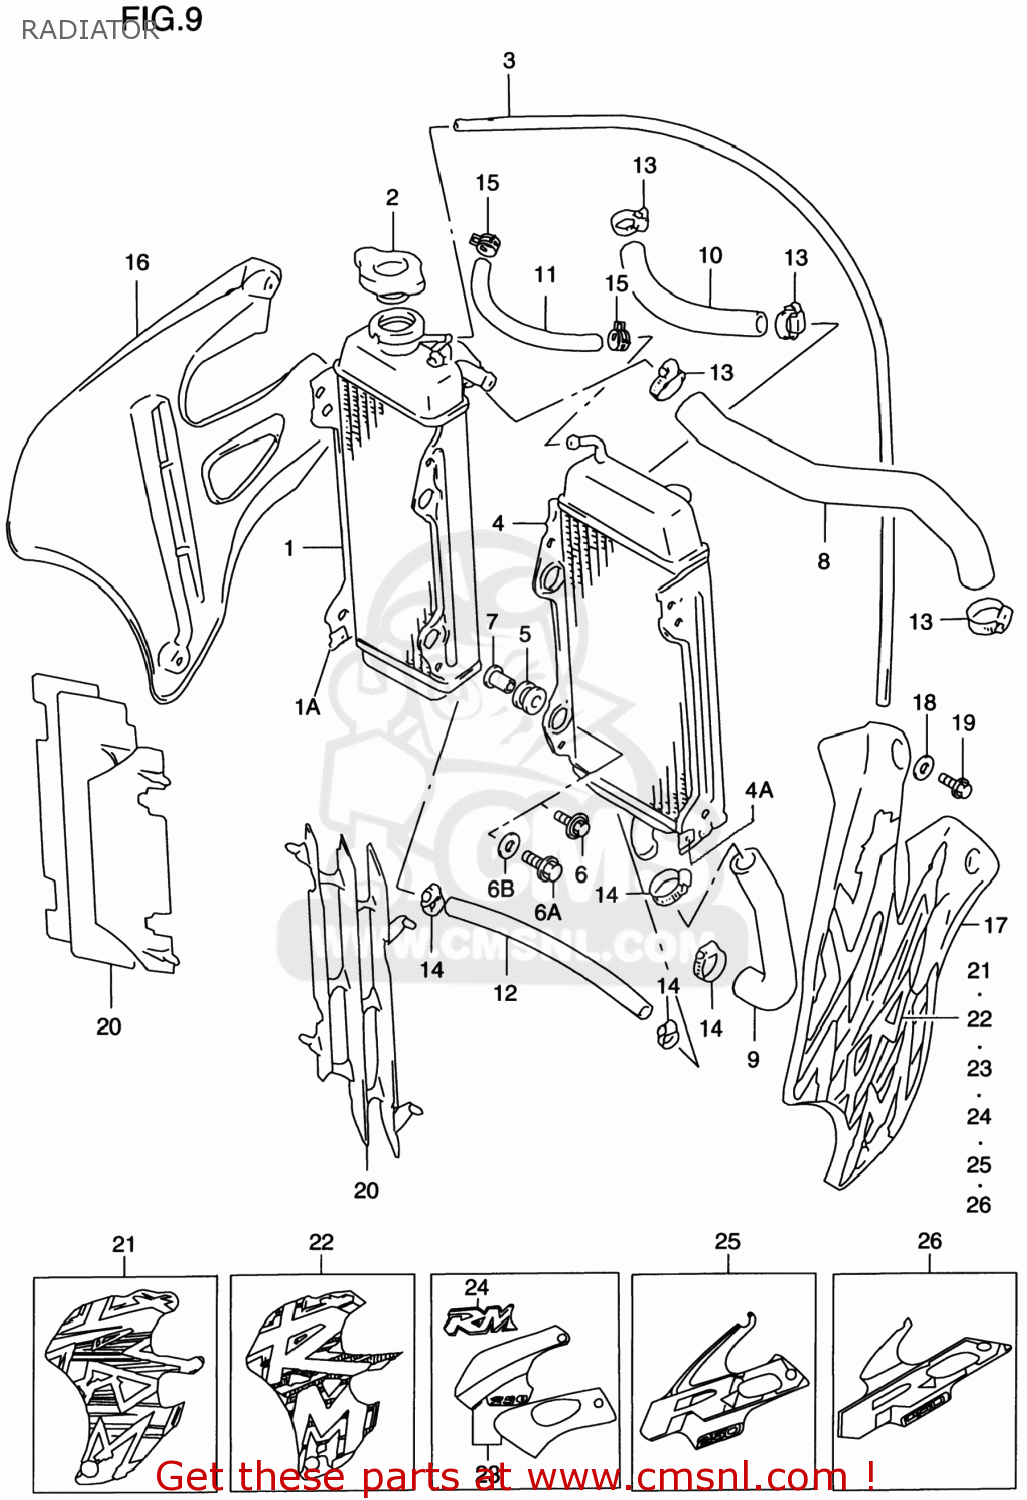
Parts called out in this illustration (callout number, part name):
1	RADIATOR,WATER,R
1-A	NUT
2	CAP,RADIATOR
3	HOSE(5X8X2000)
4	RADIATOR,WATER,L
4-A	NUT
5	CUSHION,RADIATOR LWR
6	BOLT(6X25)
6A	SCREW
6B	WASHER(6.5X24X1.2)
7	SPACER(6.5X10.5X14.1)
8	HOSE,RADIATOR INLET
9	HOSE,RADIATOR OUTLET
10	HOSE,RADIATOR JOINT NO.1
11	HOSE,RADIATOR BYPASS
12	HOSE,RADIATOR JOINT NO.2
13	CLAMP
14	CLAMP
15	CLIP
16	COVER,RADIATOR,RIGHT
17	COVER,RADIATOR,LEFT
18	WASHER
19	BOLT
20	LOUVER,RADIATOR
21	EMBLEM,RADIATOR COVER
22	EMBLEM,RADIATOR COVER,R
23	TAPE SET,RADIATOR COVER
24	EMBLEM,RADIATOR COVER,R
25	TAPE,RADIATOR COVER,LEFT
26	TAPE,RADIATOR COVER,R
